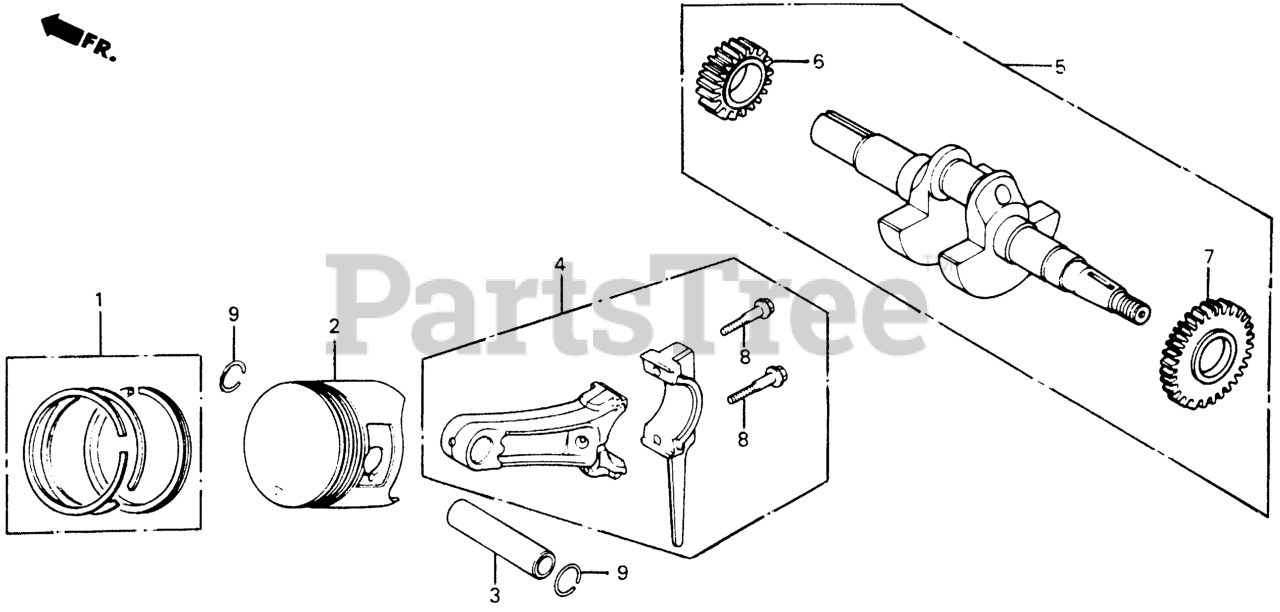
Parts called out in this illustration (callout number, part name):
1	RING SET, PISTON (STD)
1	RING SET, PISTON (OS 0.25) (NIPPON) Use up to Engine SN 2120317.
1	RING SET, PISTON (OS 0.25) (TEIKOKU) Use up to Engine SN 2120317.
1	RING SET, PISTON (OS 0.50) (NIPPON) Use up to Engine SN 2120317.
1	RING SET, PISTON (OS 0.50) (TEIKOKU) Use up to Engine SN 2120317.
1	RING SET, PISTON (OS 0.75) (NIPPON) Use up to Engine SN 2120317.
1	RING SET, PISTON (OS 0.75) (TEIKOKU) Use up to Engine SN 2120317.
1	RING SET, PISTON (OS 0.25)
1	RING SET, PISTON (OS 0.50) Use from Engine SN 2582392.
1	RING SET, PISTON (OS 0.50) (TEIKOKU)
1	RING SET, PISTON (0.75) (NIPPON) (NA USE ALT:13013-ZE1-014)
1	RING SET, PISTON (0.75) (TEIKOKU)
2	PISTON (STD)
2	PISTON (0.25)
2	PISTON (0.50)
2	PISTON (0.75) Use up to Engine SN 2120317.
2	PISTON (0.75)
3	PIN, PISTON
4	ROD ASSY., CONNECTING (0.25 LOWER SIZE) (NOT AVAILABLE)
4	ROD ASSY., CONNECTING
5	CRANKSHAFT
6	GEAR, TIMING
7	GEAR, GOVERNOR DRIVE
8	BOLT, CONNECTING ROD
9	CLIP, PISTON PIN (18MM)
